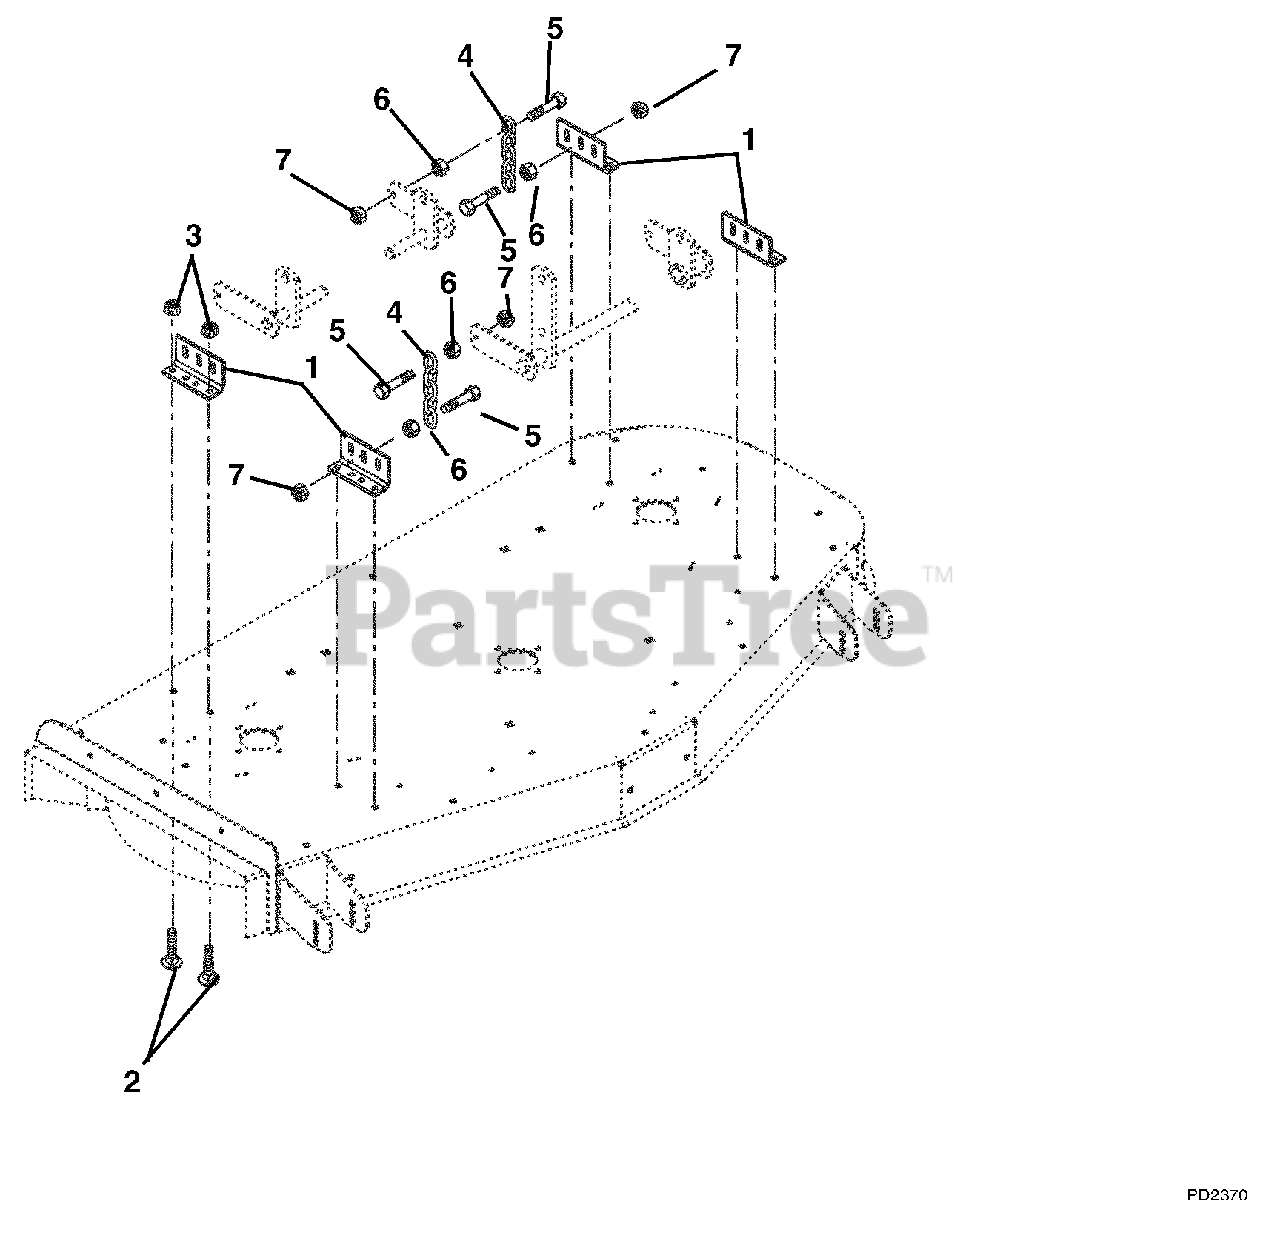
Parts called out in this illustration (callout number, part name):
1	Bracket, Mower Mounting
2	Bolt-Round Head Square Neck .38-16 x 1.00 Grade 5 (036, 038, 309)
3	Nut-Locking-Top-Flange .38-16
4	Chain, Link
5	Bolt-Hex .50-13 x 2.00 Grade 5
6	Nut-Spin Lock-Flange 0.5-13
7	Nut-Locking-Top-Flange 0.50-13
